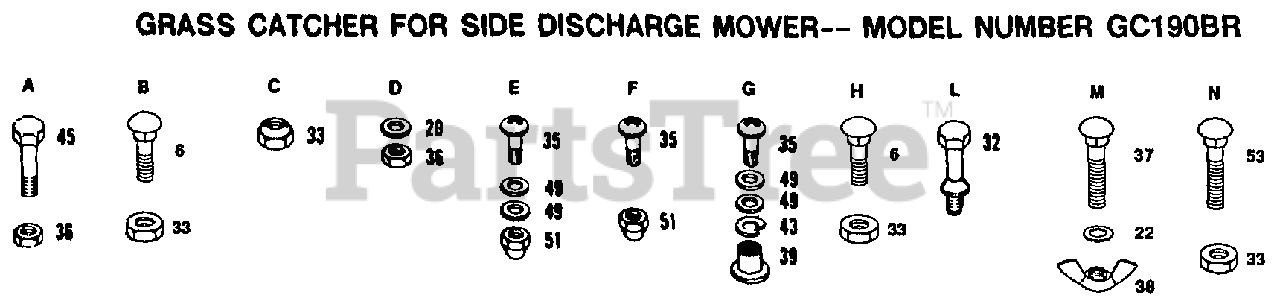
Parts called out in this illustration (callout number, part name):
6	BOLT
20	WASHER
32	LATCH RB
35	SCREW.TRHD.10-24
37	BOLT
39	WELDNUT
43	LOCKWASHER
49	WASHER
53	BOLT CRT
